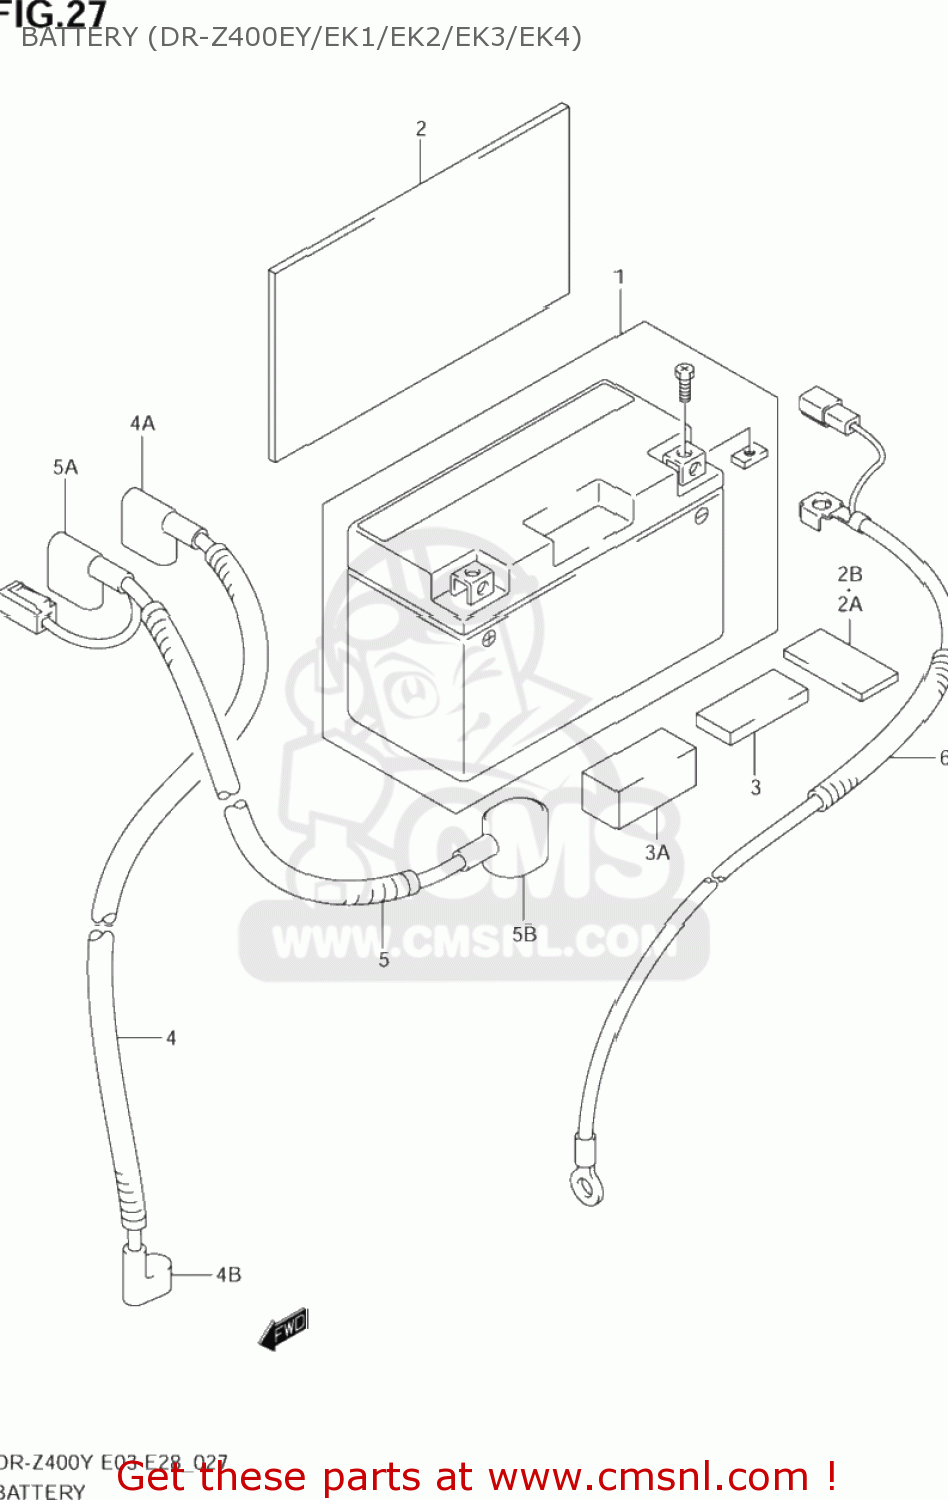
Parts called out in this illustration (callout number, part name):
1	BATTERY ASSEMBLY
2	PROTECTOR(170X95X3.0)
2A	PROTECTOR(30X80X1)
2B	PROTECTOR(80X80X2)
3	PROTECTOR,BATT
3A	DAMPER,HEADLAMP HOUSING BRACKET
4	WIRE,STARTER MOTOR LEAD
4A	CAP,STARTER RELAY
4B	CAP,STARTER MOTOR
5	WIRE,BATTERY PLUS LEAD
5A	CAP,STARTER RELAY
5B	CAP,BATTERY PLUS
6	WIRE,BATTERY MINUS LEAD
